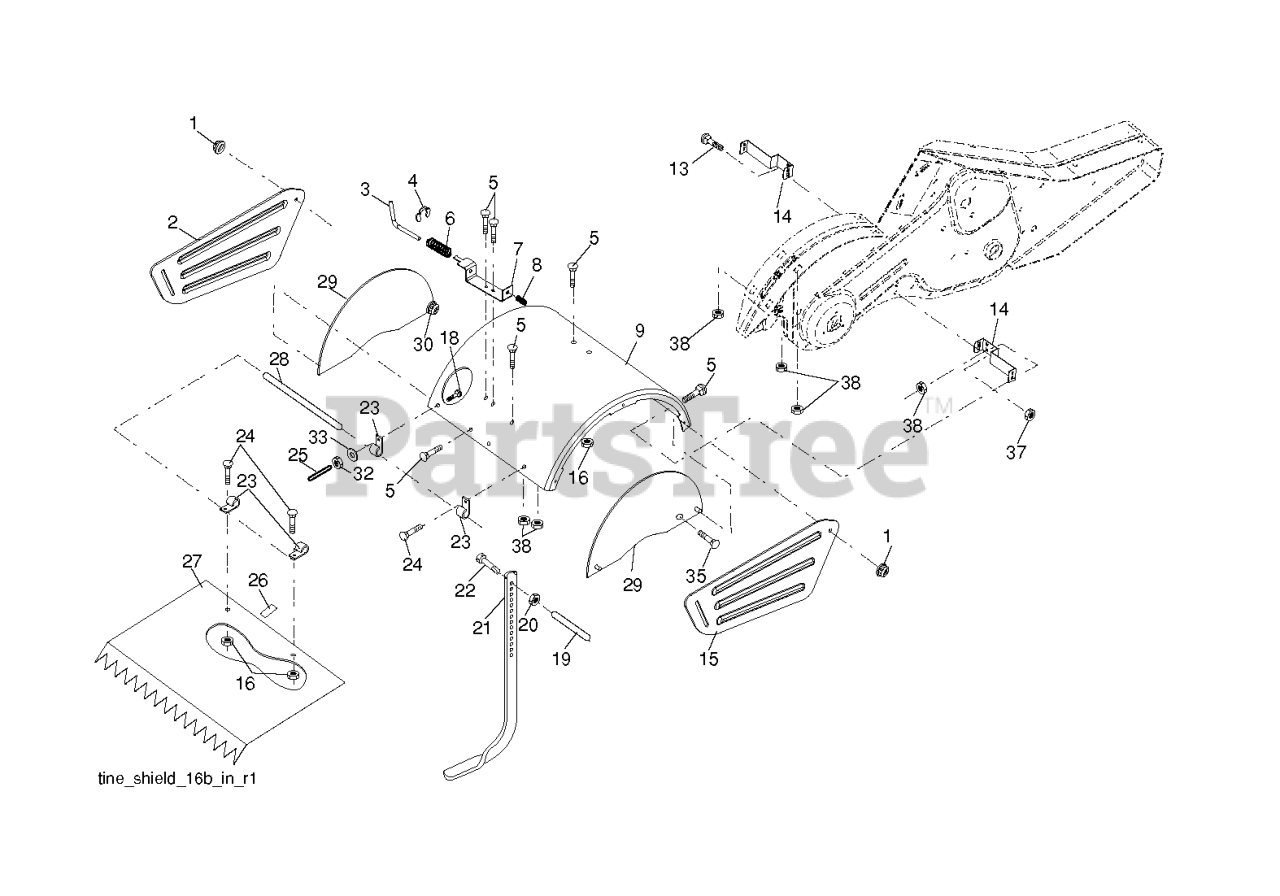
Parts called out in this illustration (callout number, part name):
1	NUT LOCK HEX FLANGE 5/16-18
2	SHIELD.SIDE.OUTER.LH.RED
3	STAKE PIN TI
4	RING, KLIP
5	BOLT, RDHD SQNK 5/16-18 X 3/4
7	BRACKET.LATCH.STAKE.3.20.BLACK
8	SPRING CRT
9	RP.SHIELD.ASM.PNT.SIDE.RED
13	BOLT.CARRIAGE.5/16-18
14	BRACKET.TINE.SHIELD.TILLER.BLA
15	SHIELD.SIDE.OUTER.RH.RED
16	NUT T
20	NUT.HEX.3/8-16UNC
21	STAKE.DEPTH.16.CRT.BLACK
22	BOLT.375-16
24	BOLT
25	VINYL CAP TI
26	PAD IDLER TI
27	SHIELD.LEVELING.TILLER.RED
28	PIN.HINGE.TILLER
29	RP.SHIELD.ASM.PNT.SIDE.RED
30	LOCKNUT-FLANGE 5/16-18
32	NUT
33	LOCKWASHER
35	BOLT.CARR.5/16-18X5/8.SHORT
37	NUT.71038.31-18.HEX.NYLOCK
38	NUT
